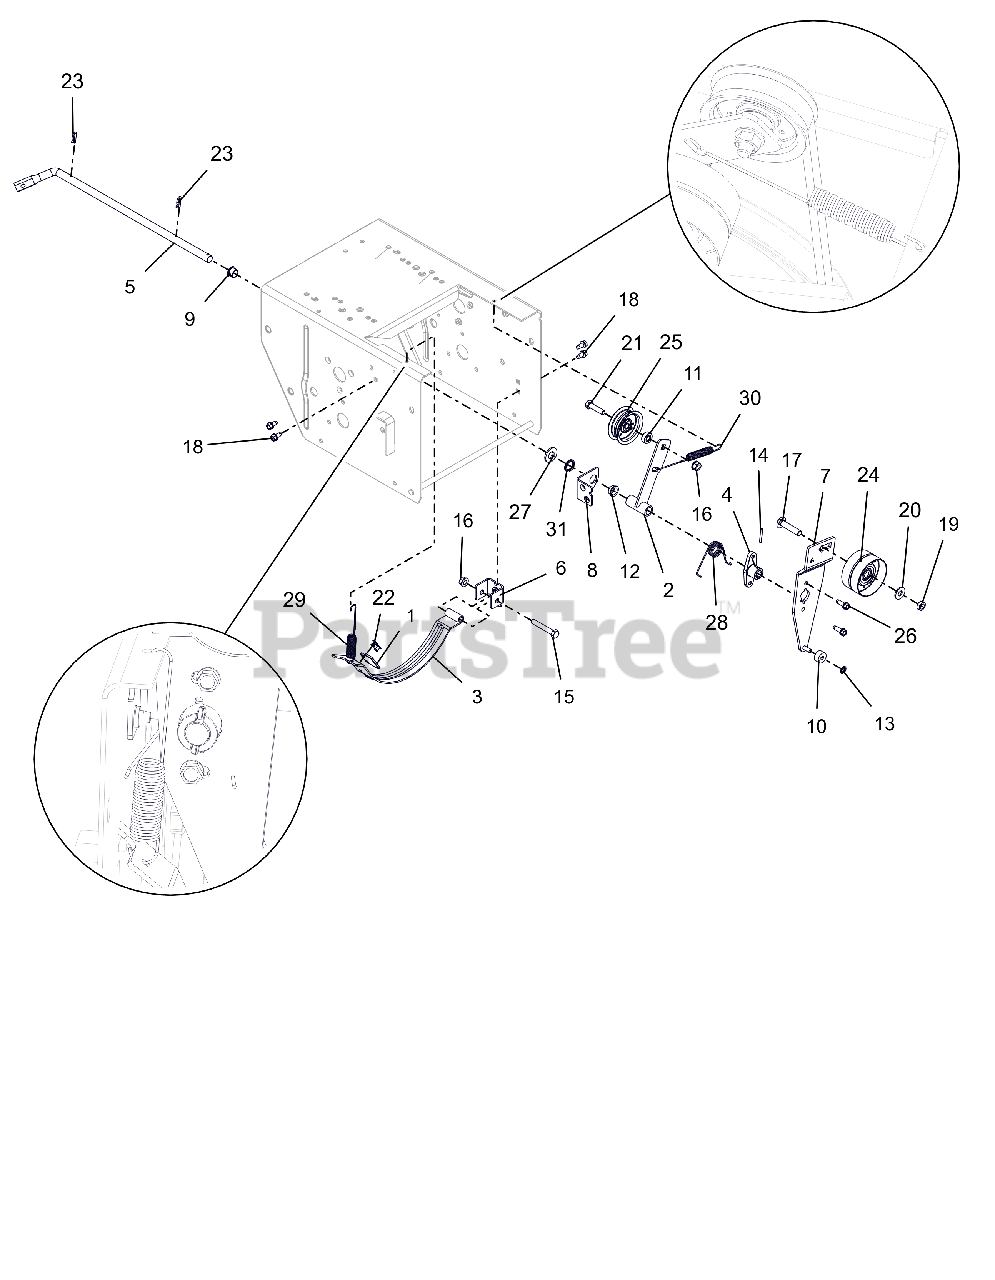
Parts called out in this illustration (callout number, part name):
1	PAD, BRAKE
2	ARM, IDLER-TRACTION
3	ARM, BRAKE-ATTACHMENT
4	HUB, BRAKE ARM
5	ARM, ATTACHMENT
6	PIVOT, BRAKE
7	ARM, IDLER-ATTACHMENT
8	BRACKET, SUPPORT
9	BUSHING, POLYLINER-.50 SPLIT
10	BSHG,SLV .265 X .625 X .375
11	SPCR, BRG .315X.500X.358X.281
12	BSHG,FLANGE .500X.625X.270X.75
13	RG-RTNG-EXT .250X.010
14	PIN-ROLL .125X1.00
15	BLT, HEX .31-18X2.00 G5 ZCC
16	NUT-LK-TOP-FLG .312-18 GF ZCC
17	@BLT-RHDSSQNK .38-16X1.75 G5YZ
18	SCR-TAP .25-20X.50 HWH ZCC
19	NUT-LK-CTR-JAM .375-16 GB ZCC
20	WSHR,FLT .375X.875X.083 ZCC
21	BLT, HEX .31-18X1.25 G5 ZCC
22	RVT-POP .187 YZ
23	CLIP, SPRING
24	IDLER, FLAT-2.75 OD X .375 ID
25	IDLER, FLAT - 2.00"
26	SCR,TAP .25-20X.75 HWH TR ZCC
27	WSHR,FLT .531X1.062X.095 ZCC
28	SG-TORS .067X.88
29	SG-TENS .056X.60X4.40
30	SG-TENS .06X.482X5.35
31	WAVE SPRING .600X.875X.25FH
